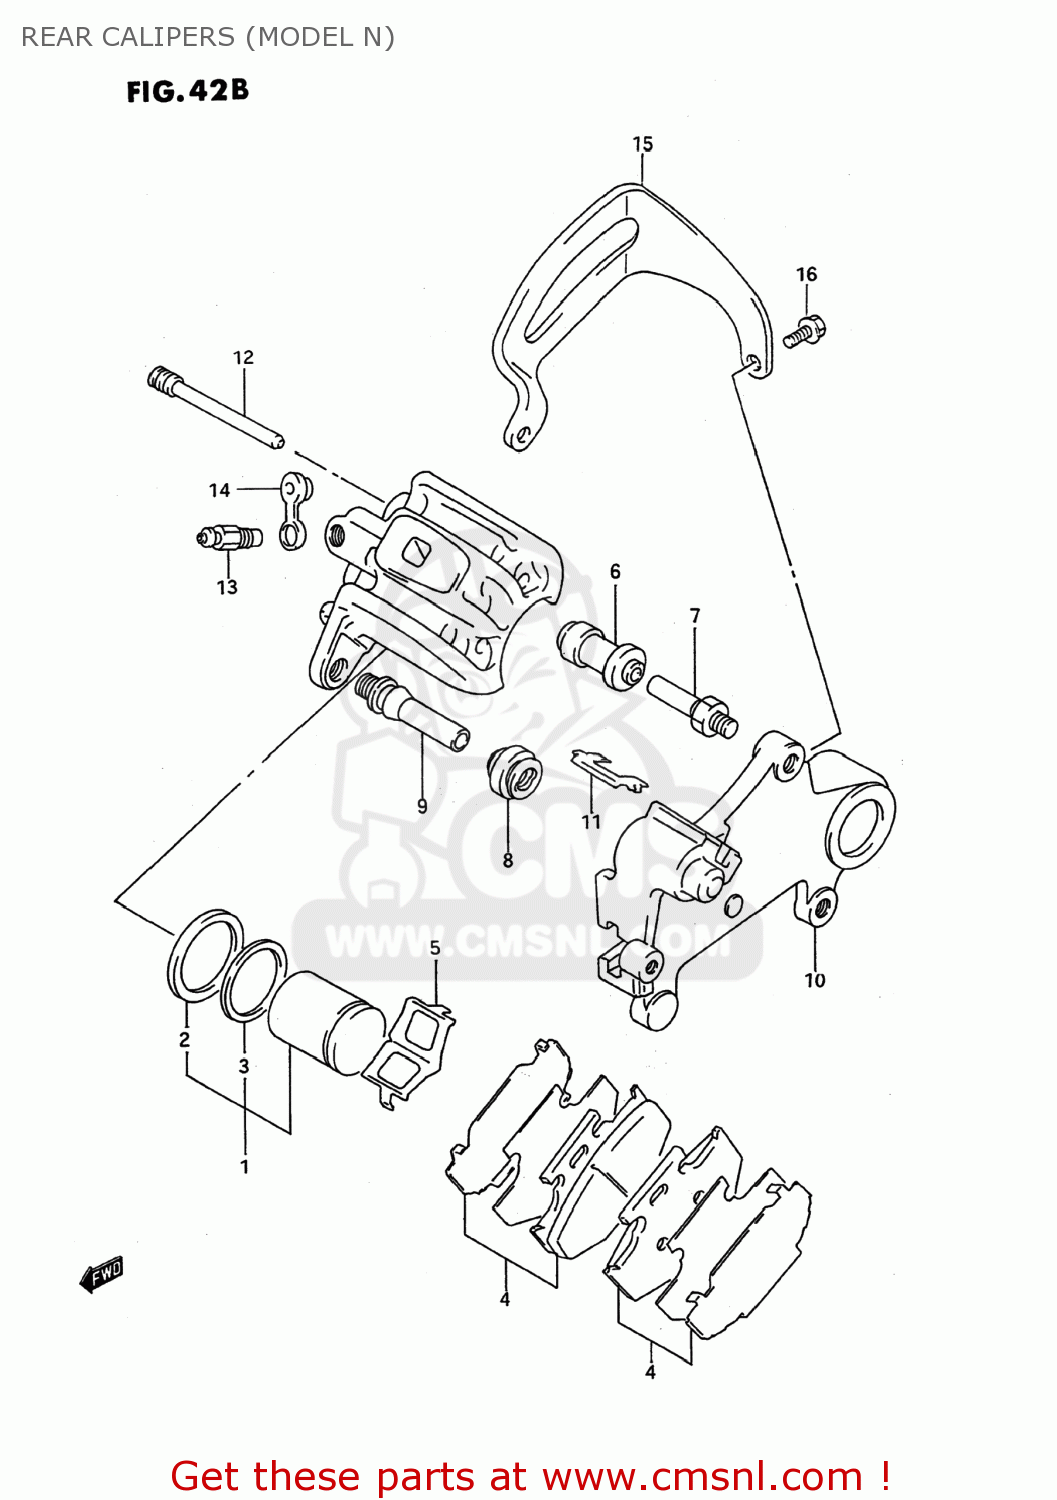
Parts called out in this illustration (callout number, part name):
1	PISTON SET
2	SEAL,PISTON
3	SEAL,DUST
4	PAD & SHIM SET (NAS)
5	SPRING,PAD
6	BOOT
7	PIN,BOLT
8	BOOT
9	PIN
10	BRACKET
11	RETAINER,BRACKET
12	PIN,HANGER
13	BLEEDER
14	CAP,BLEEDER
15	GUARD,RR CALIPER
16	BOLT
